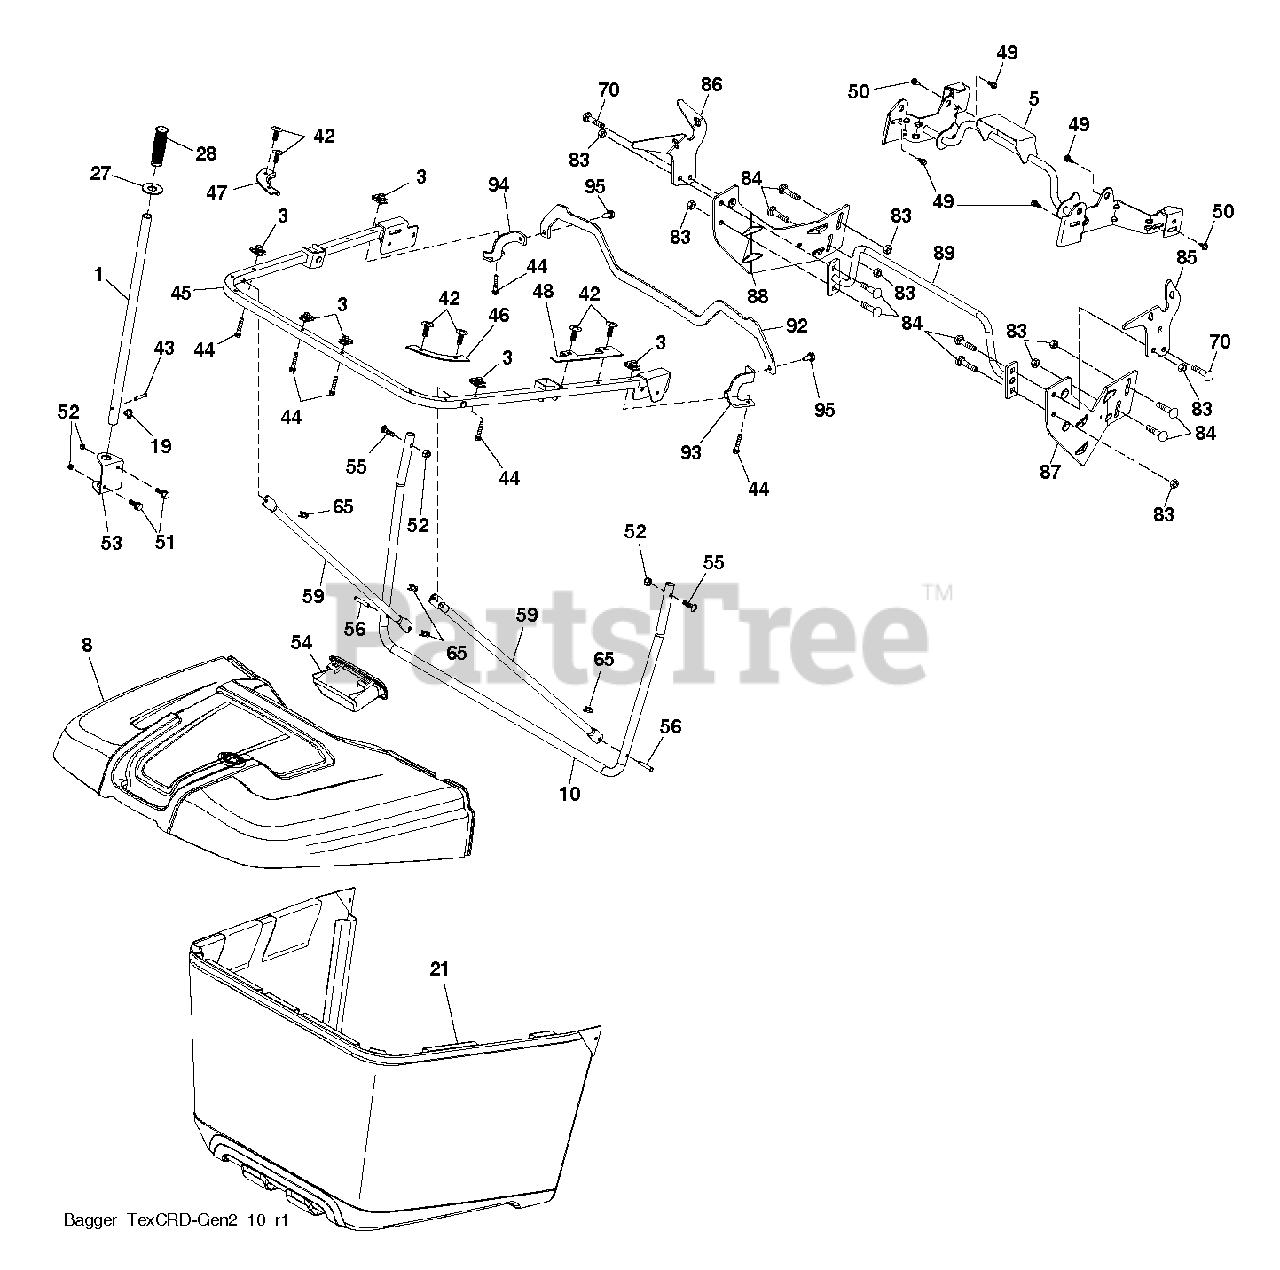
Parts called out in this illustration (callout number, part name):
1	TUBE.HANDLE.BAGGER.CRD/SRD.BLA
3	1/4-20 U NUT
5	FRAME TEX_CRD_GEN2 UPPER PIVOT
8	COVER.BAG.NO_APP.CRD.GENII.498
10	FRAME TEX_CRD_GEN2 BAGGER FRAM
19	PIN.COTTER.5/16.BOW TI
21	BAGGER.ASM.FABRIC.CRD.GII.HUSQ
27	GROMMET RUBBER GROMMET, DUMP T
28	GRIP.HANDLE.BLACK
42	CLIP CHRISTMAS TREE CLIP
43	RIVET,DRILLED
45	FRAME TEX_CRD_GEN2 UPPER U FRA
46	CONNECTOR RIGHT BAGGER CORNER
47	CONNECTOR LEFT BAGGER CORNER C
48	BAFFLE BAGGER SIDE CLOSE-OUT
49	BOLT, SHOULDER 5/16-18
50	BOLT, 5/16-18 X 1 3/4
51	BOLT.CARR.SQNK.5/16-18UNC.X3/4
52	NUT.71038.31-18.HEX.NYLOCK
53	BRACKET DUMP HANDLE BRACKET, T
54	HANDLE BAGGER TOP FRONT HANDLE
55	BOLT
56	PIN.CLEVIS.183
59	TUBE BAGGER SPREADER TUBE, TEX
65	RETAINER M
70	SCREW, 3/8-16X3/4
83	NUT
84	BOLT D
85	BRACKET.RH.PIVOT.MAN.DUMP.BLAC
86	BRACKET.LH.PIVOT.MAN.DUMP.BLAC
87	BRACKET.RH.MID.SUP.BAG.TEX.CRD
88	BRACKET.LH.MID.SUP.BAG.TEX.CRD
89	TUBE.WELD.OFSET.STRUT.BAG.X431
92	BRACKET.PNT.BAGGER.TOP.SUPPORT
93	BRACKET.PNT.RH.SUPPORT.ATTACH
94	BRACKET.PNT.LH.SUPPORT.ATTACH
95	SCREW
